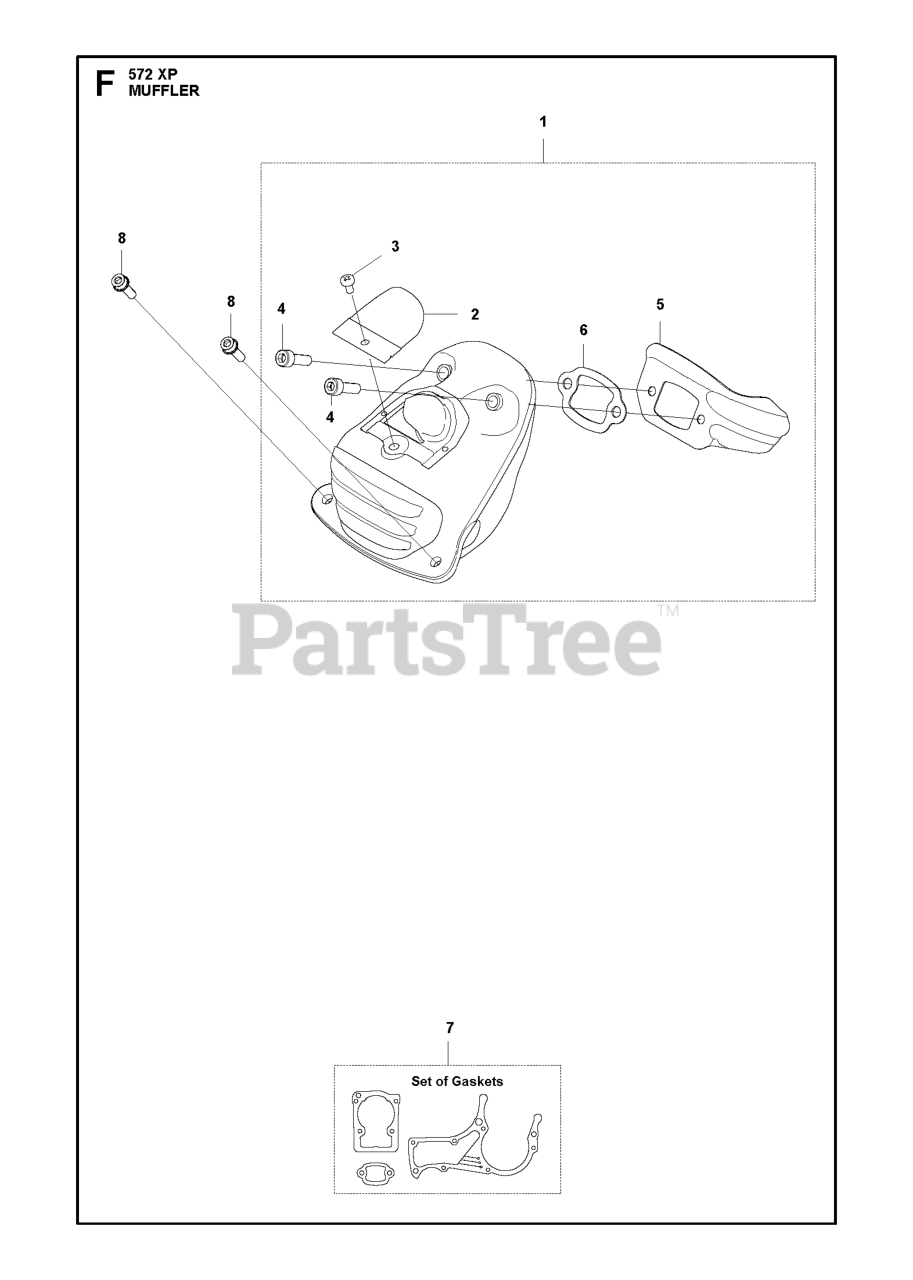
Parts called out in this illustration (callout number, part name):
1	MUFFLER KIT
2	SPARK ARRESTER
4	SCREW ITXSCM M6X50 T27 12.9 T
5	HEAT DEFLECTOR MUFFLER A054
6	GASKET MUFFLER A054
7	GASKET KIT H565/H572
8	SCREW ITXSCM M6X30 T27 10.9 Z
